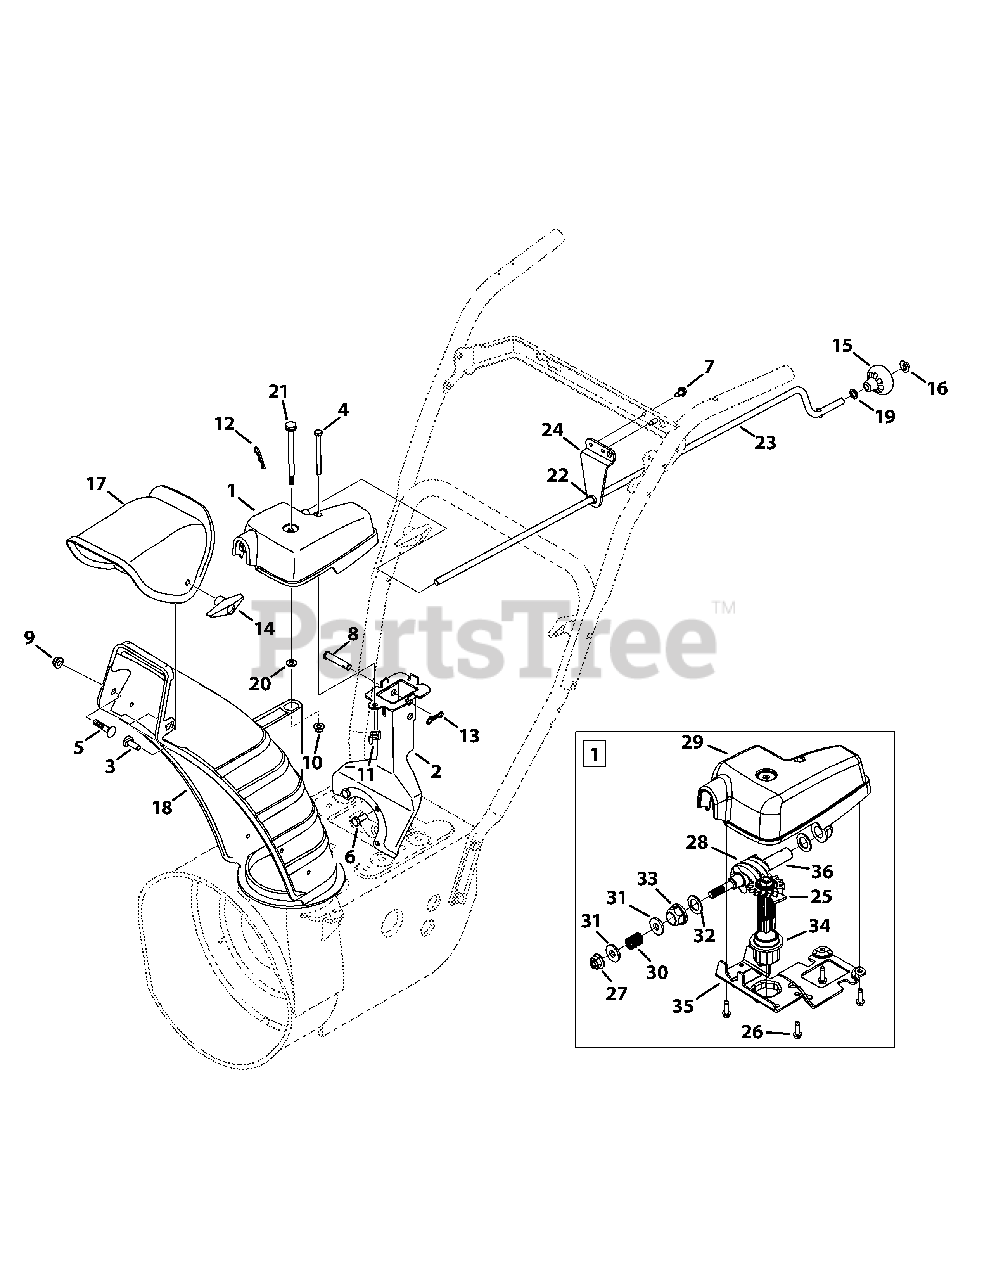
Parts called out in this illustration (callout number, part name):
1	Chute Rotation Gear Box
2	Chute Support Bracket (large block engine)
2	Chute Support Bracket (small block engine)
3	Carriage Bolt, 5/16-18 x 1.00
4	Hex Screw, 1/4-20 x 3.00
5	Carriage Bolt, 5/16-18 x .750
6	Hex Lock Screw, 5/16-24 x .750
7	Hex Washer Screw, 1/4-20 x .625
8	Clevis Pin, 3/8-1.87
9	Flange Lock Nut, 5/16-18
10	Flange Lock Nut, 1/4-20
11	Wing Nut, 1/4-20
12	Cotter Pin, .08 x 1.42
13	Bow-tie Cotter Pin
14	Wing Knob, 5/16-18
15	Shift Knob, .390
16	Push Cap, 3/8
17	Upper Chute
18	Lower Chute, 5.0
19	Flat Washer, .375 x .738 x .063
20	Flaw Washer, .25 x .630 x .0515
21	Shoulder Screw, .312 x 3.5 x 1/4-20
22	Plastic Bushing, .380 ID
23	Chute Crank
24	Support Rod Bracket
25	Gear Assembly
26	Screw, 12-16 x .75
27	Flange Lock Nut, 3/8-16
28	Worm
29	Gear Cover
30	Compression Spring, .39 x .60 x .88
31	Flat Washer, .380 x .93 x .110
32	Flat Washer, .625 x 1.0 x .067
33	Hex Bearing
34	Flange Bearing
35	Gear Bracket
36	Worm Shaft
